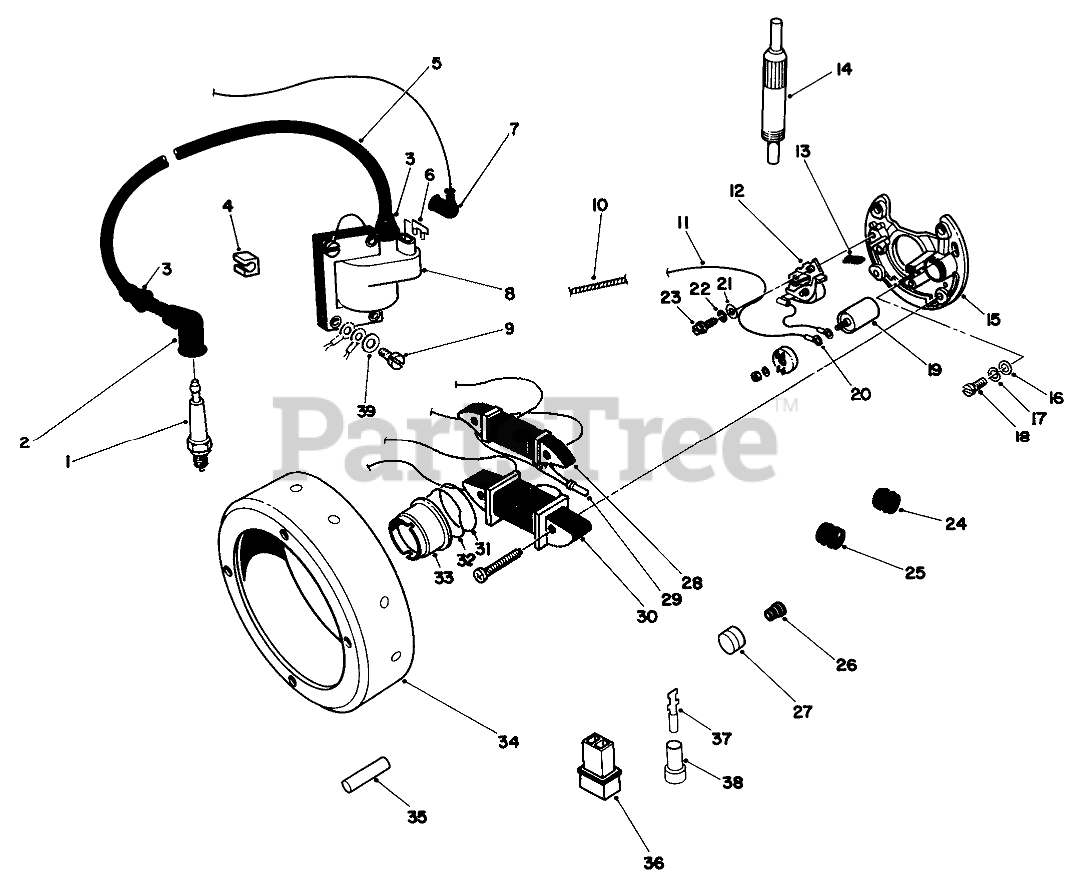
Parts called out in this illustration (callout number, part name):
1	Spark Plug
2	SPARK PLUG CAP
3	Rubber Socket
4	Clamp
5	Cable-Ignition
6	Connector
8	Coil-Ignition
9	Capscrew-Socket Head
10	Band-Spiral
12	POINT SET
13	Lubricating Wick
14	Gauge-Timing
15	Plate-Armature
16	Washer
17	Lockwasher
18	Socket-Capscrew
19	Condenser
20	Terminal
21	Washer
22	Lockwasher
23	Capscrew-Socket Head
24	Grommet
25	Grommet
26	Grommet
28	Lighting Coil
29	Connector
30	Coil-Lighting
31	Washer
32	Locking Ring
34	Flywheel-Magnetic
35	Sleeve
36	Connector
38	Connector
39	WASHER-FLAT
